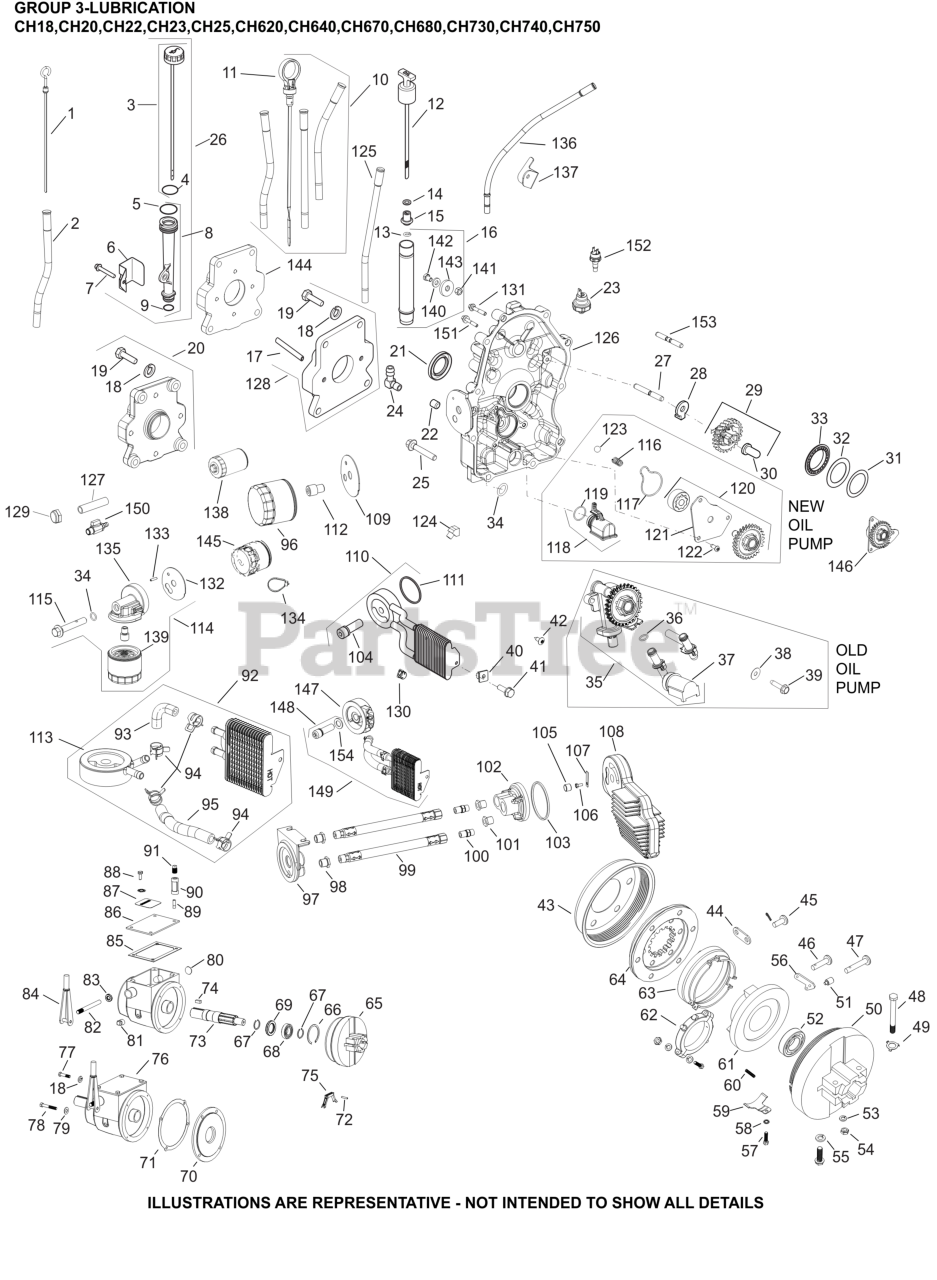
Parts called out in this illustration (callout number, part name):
10	KIT, DIPSTICK/DIPSTICK TUBES
22	PLUG, CTSK PIPE 1/8"
23	SENSOR, OIL PSI
25	SCREW, FLG M8X1.25X45
28	TAB, LOCKING
29	KIT, GOVERNOR GEAR W/PIN
30	PIN, GOVERNOR REGULATING
40	NUT, PLASTIC - BLACK
41	SCREW, HEX HEAD
93	KIT, HOSE 140MM
96	OIL FILTER
111	O-RING, OIL COOLER
116	SPRING, COMPRESSION
117	SEAL, OIL PUMP COVER
118	PICK-UP ASSEMBLY, OIL
119	O-RING, OIL PICK-UP
120	PUMP ASSEMBLY, OIL
121	COVER, OIL PUMP
122	SCREW, BUTTON HEAD
123	PRESSURE RELIEF BALL
126	CLOSURE PLATE ASSEMBLY (SERVICE)
130	CLAMP, HOSE LOW PROFILE
131	SCREW, HEX FLANGE
148	KIT, OIL FILTER NIPPLE
149	KIT, OIL COOLER
NI	SHAFT, GOVERNOR GEAR
NI	WASHER, FLAT
